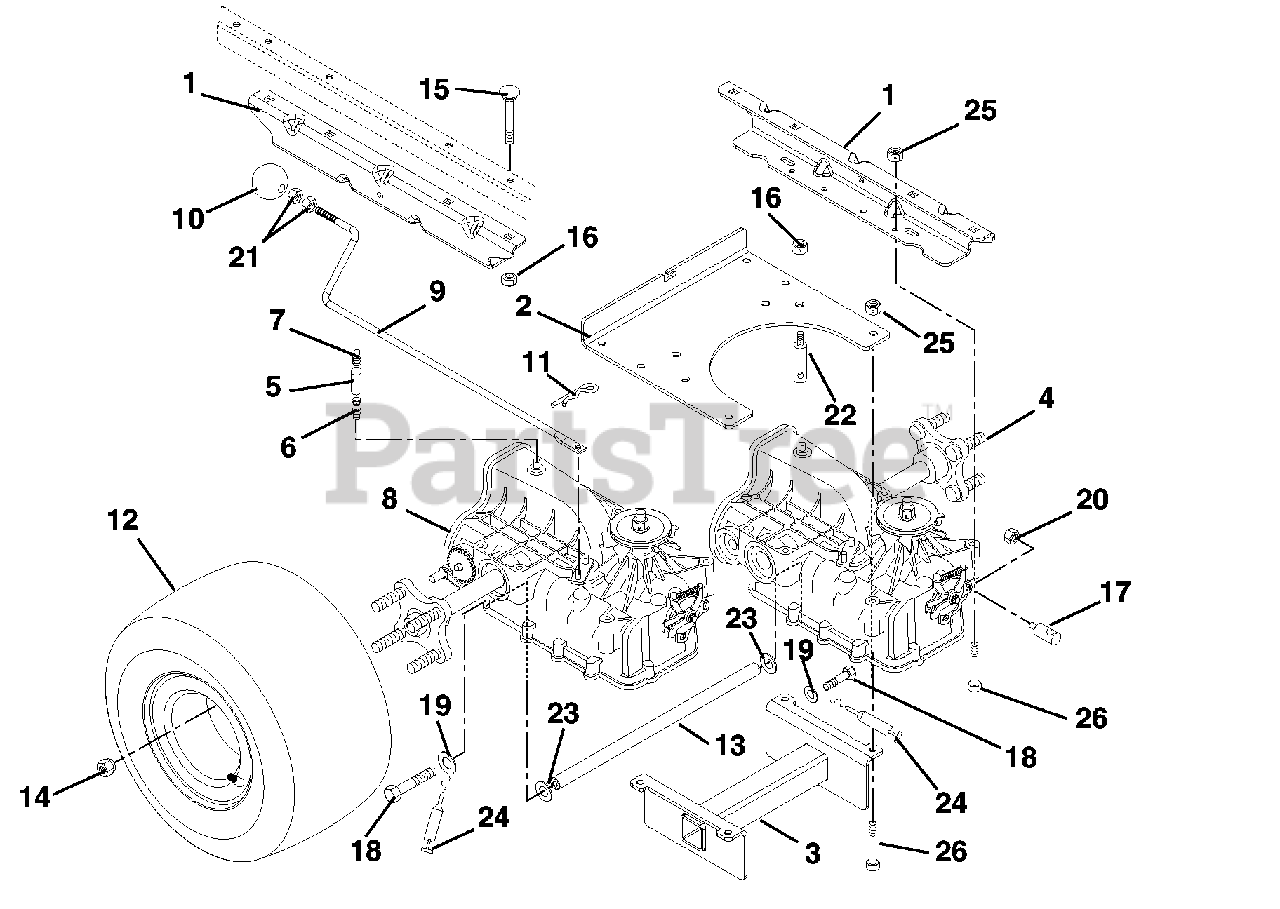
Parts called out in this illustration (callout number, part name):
1	BKT-TRANS AXLE
2	BKT-TRANS AXLE SUPPORT
3	WLDMT-TRANS AXLE BRACE
5	HOSE - VENT
6	FTG-STR .50 O-RING
7	CAP-VENT .50
9	ROD-DUMP IZT
10	KNOB, BALL 5/16-18 X 1.5
11	PIN-HAIR, ENDRIES #25 YWZC
12	ASSY-TIRE 9.5X18-2PLY
12	ASSY-TIRE 8.5X18 2PLY
13	ROD-AXLE BRACE
14	NUT-LUG .50-20 YWZC
15	@BLT-RDHDSQNK .38-16X2.25 G5YZ
16	@NUT-LK-NYL-FLG .38-16 YWZC
17	ROD PIVOT YWZC
18	@BLT-HEX .31-18X2.50 GR5 YWZC
19	@WSHR-LK .31X.078 REG YWZC
20	@NUT-LK-NYL-FLG .31-18 YWZC
21	NUT- JAM .312-18 YWZC
22	SHOULDER STUD
23	WSHR-FL-STL .328X.87X.179 YWZC
24	ADHSV SEALANT (BLUE) 250 ML
25	@NUT-LK-NYL-FLG .31-18 YWZC
26	@BLT-HEX .31-18X2.75 GR5 YWZC
